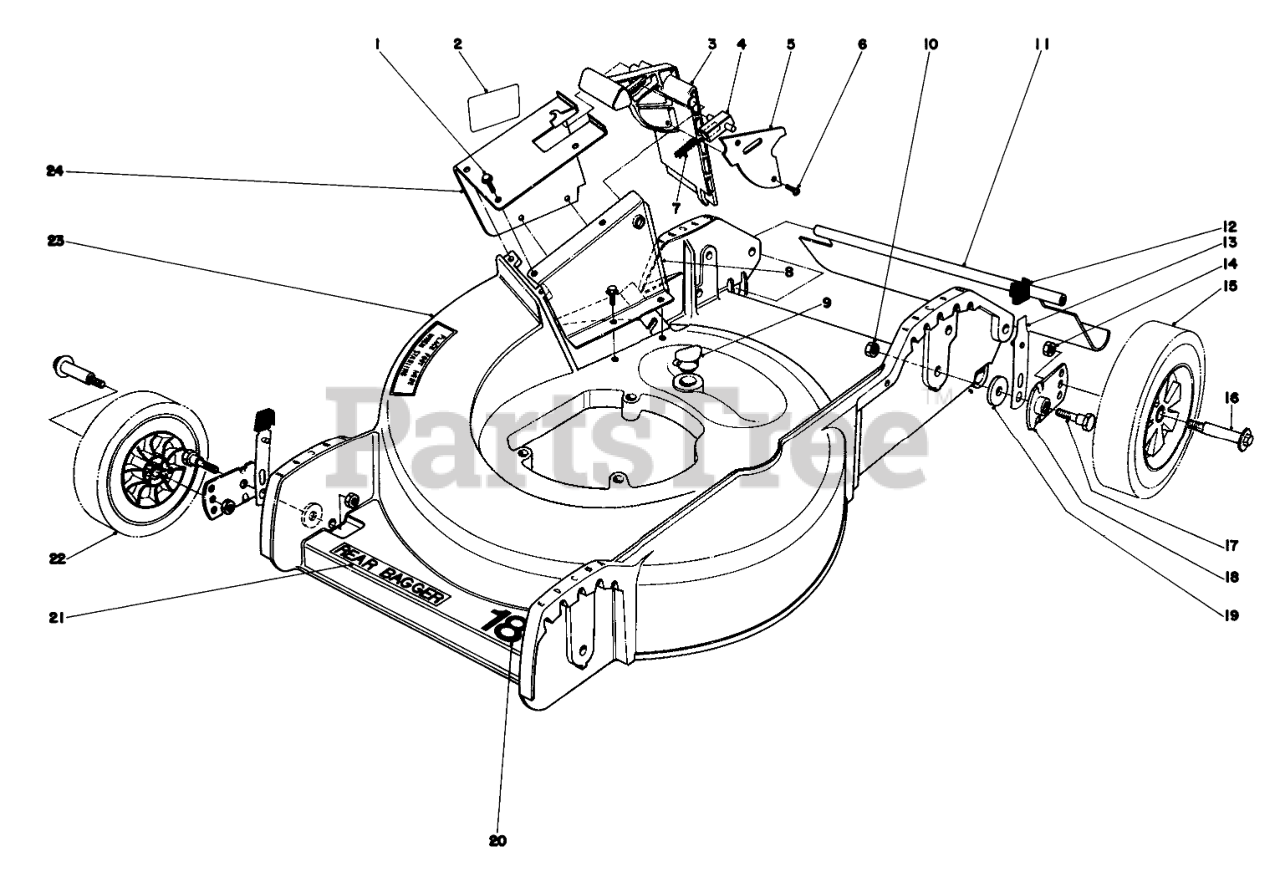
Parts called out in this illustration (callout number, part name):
1	SCREW
2	Decal Door (French & Dutch)
3	Door Mulching
4	Door Latch
5	Cover Door
7	SPRING-COMPRESSION, LATCH
8	Inner Tunnel
9	WASHOUT PLUG
10	Nut
11	SHIELD - TRAILING
12	KNOB-ARM
13	SPRING ARM ASM
14	Nut
15	WHEEL & TIRE ASM
16	BOLT-WHEEL
17	PIVOT SCREW
18	PIVOT ARM ASSY
19	PIVOT WASHER
20	Decal
21	DECK DECAL
22	Wheel & Tire Assembly
23	Housing
24	Tunnel Outer
